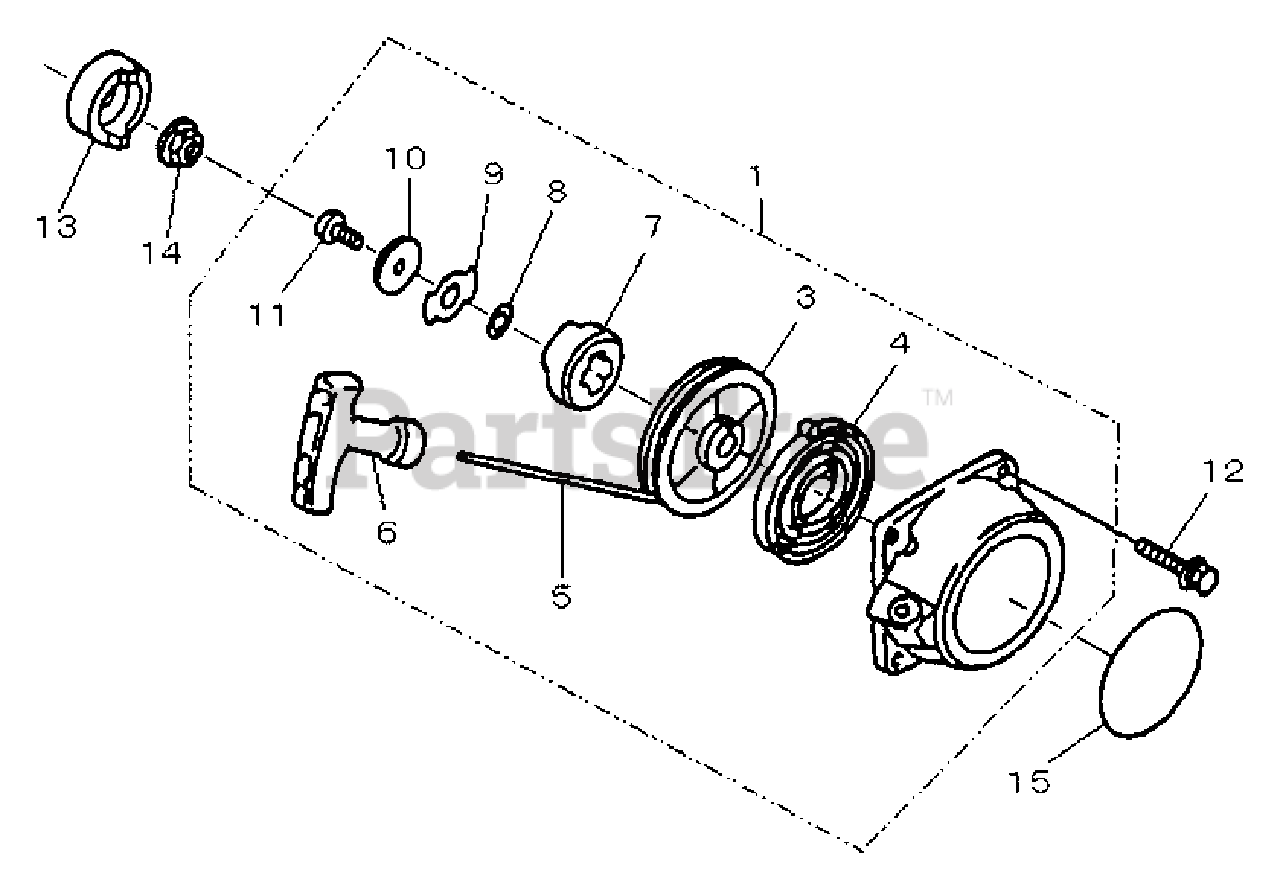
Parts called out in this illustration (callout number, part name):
1	STARTER ASSY, RECOIL
3	REEL
4	SPRING, RECOIL
6	GRIP, STARTER
7	CAM
9	RETAINER
11	SCREW M8×1.25
12	BOLT M5×20
13	PULLEY, STARTER
14	NUT, FLANGE M10
15	LABEL, TRADE
